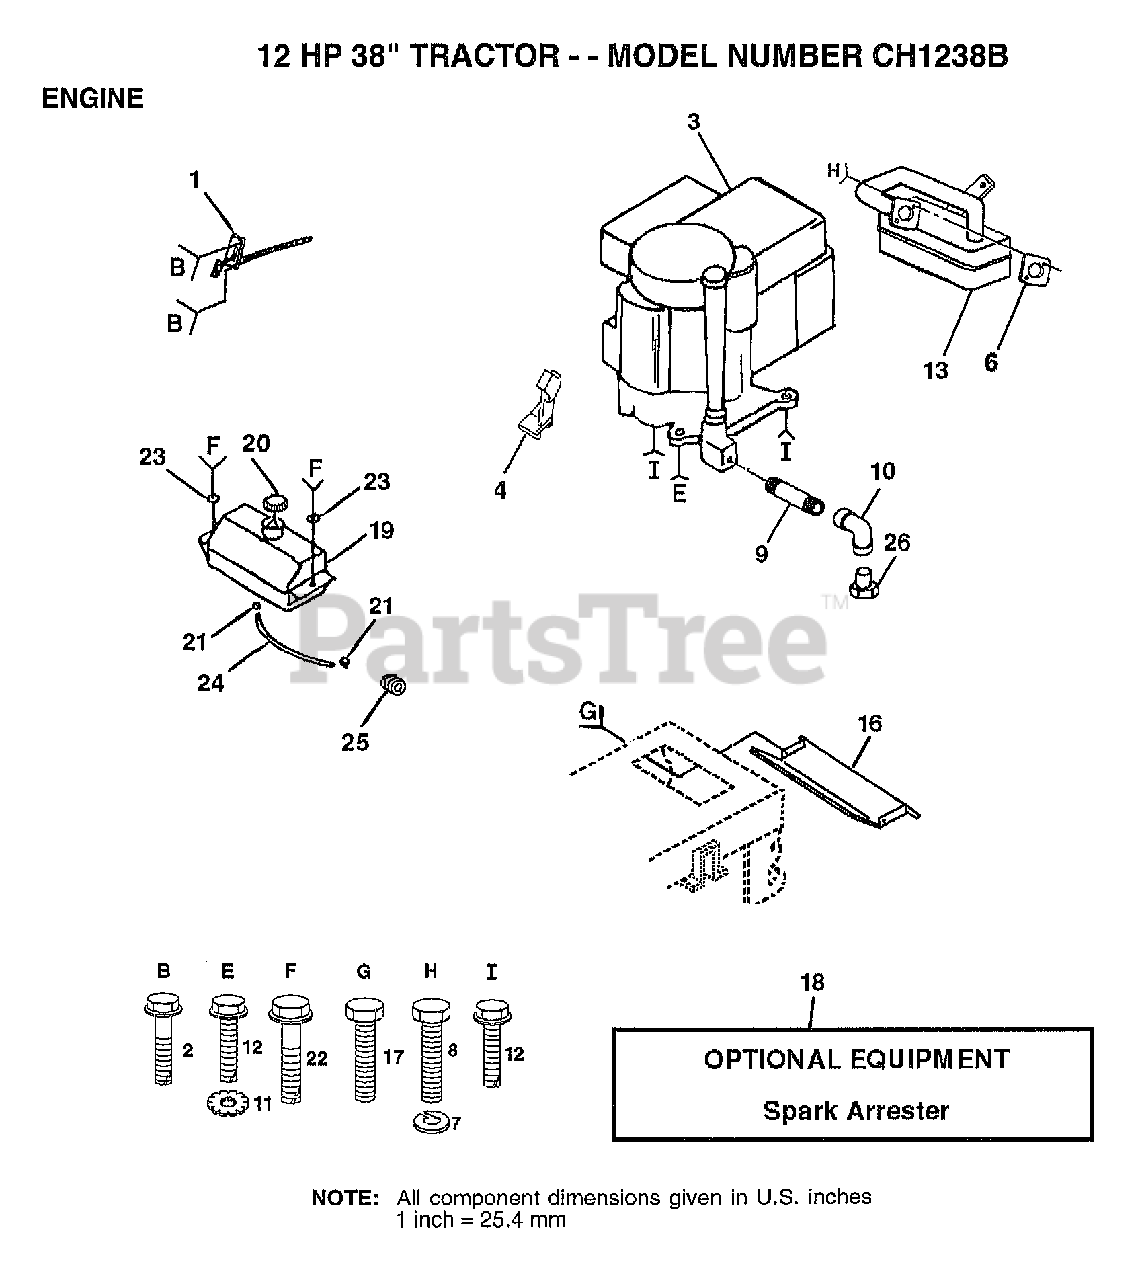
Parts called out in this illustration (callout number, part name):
2	SCREW LT
4	"STOP,DASH THROTT"
7	LOCKWASHER
8	SCREW
9	PIPE NIPPLE
10	ELBOW
11	LOCKWASHER
12	SCREW
13	MUFFLER
16	HEAT SHIELD
17	SCREW
19	TANK.FUEL.LT.
20	CAP ASM FUEL
21	HOSE CLAMP
22	SCREW HEX CRT
23	WASHER
24	LINE FUEL
